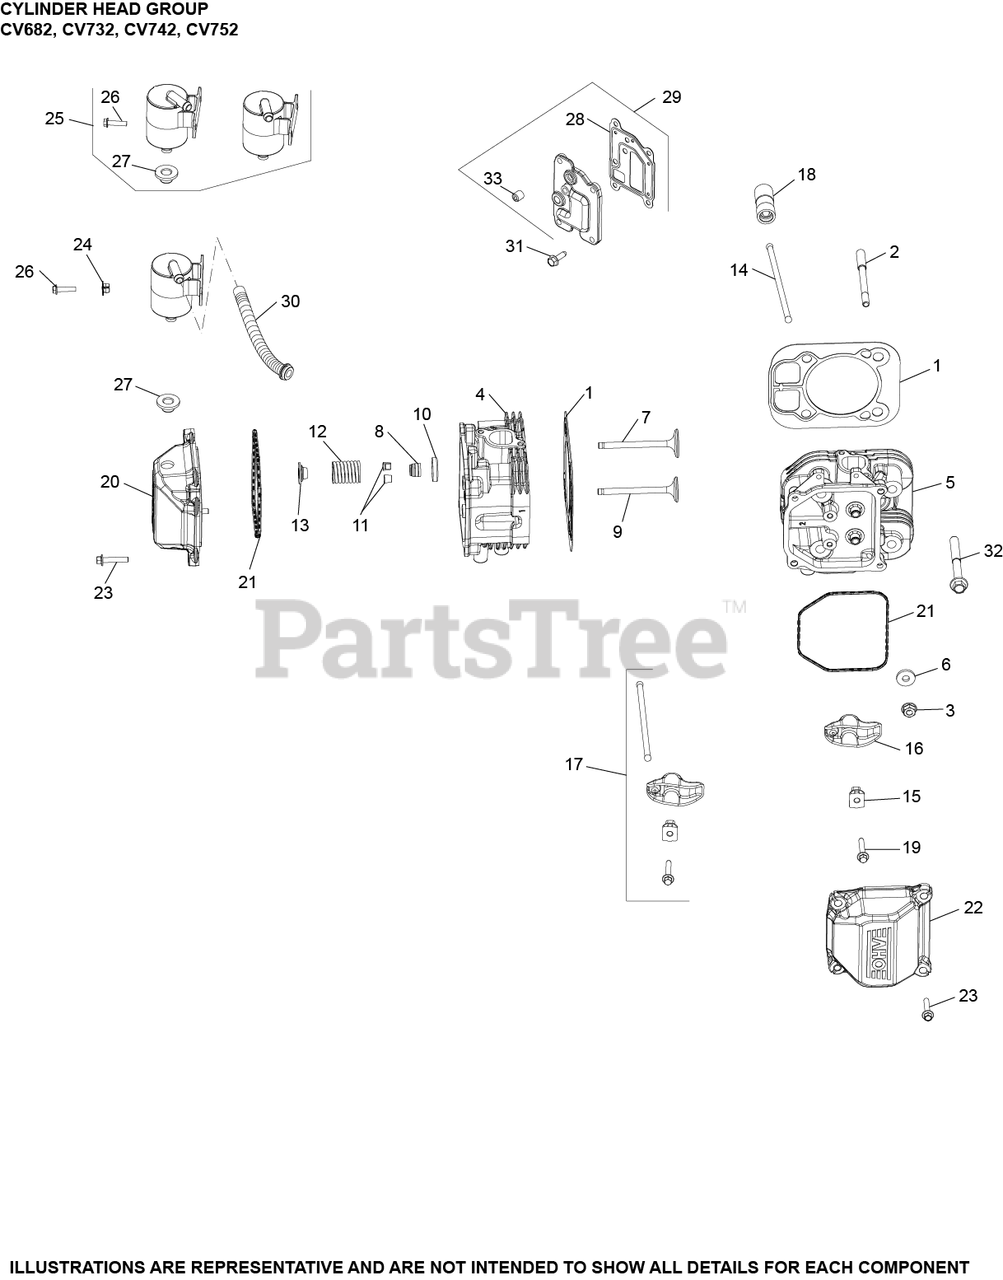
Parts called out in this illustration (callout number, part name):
1	KIT, CYLINDER HEAD GASKET
2	STUD, M8X1.25
3	NUT, FLG M8X1.25
4	KIT, CYLINDER HEAD #1
5	KIT, CYLINDER HEAD #2
6	WASHER, FLAT 8.6 MM
7	VALVE, INTAKE (STD)
7	VALVE, INTAKE (.25)
8	SEAL, VALVE BAND
9	VALVE, EXHAUST (STD) - USE 32 016 01-S
9	VALVE, EXHAUST (.25)
10	RETAINER, SPRING
11	KIT, RETAINER
12	SPRING, VALVE
13	CAP, VALVE SPRING
14	ROD, PUSH
15	PIVOT, ROCKER ARM
16	ARM, ROCKER
17	KIT, VALVE TRAIN
18	LIFTER, VALVE HYDRAULIC - (#2535111S)
19	SCREW, FLG M6X1.0X34
20	KIT, VALVE COVER
21	O-RING (YELLOW), VALVE COVER
22	KIT, VALVE COVER-PLAIN
23	SCREW, FLG M6X1.0X30
24	NUT, PLASTIC
25	KIT, BREATHER SEPARATOR
26	SCREW, HEX FLANGE HI-LO
27	GROMMET, RUBBER
28	GASKET, BREATHER
29	KIT, BREATHER COVER
30	HOSE, BREATHER VERTICAL HDAC
31	SCREW, THREAD FORMING
33	PLUG, CTSK PIPE 1/8"
